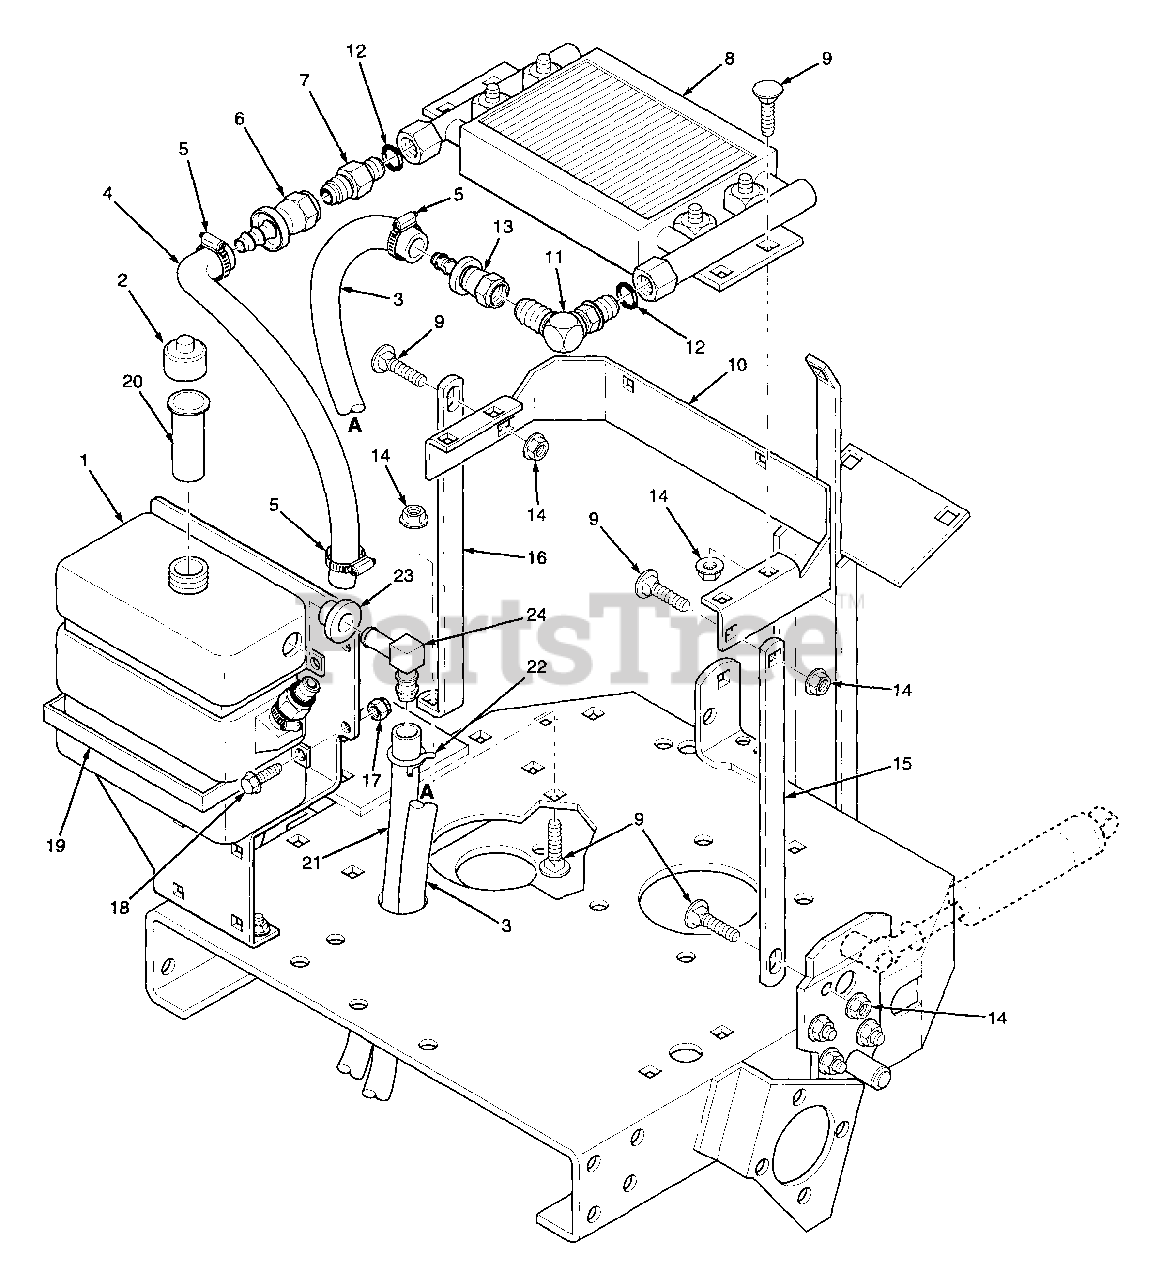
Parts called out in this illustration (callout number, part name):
1	Tank, Hydraulic
2	Cap, Hydraulic Tank
3	Hose, Pump to Oil Cooler
4	Hose, Oil Cooler to Tank
5	Clamp, Hose
6	Coupling, Flare Swivel
7	Tube, Union
8	Oil Cooler Assembly
9	Carriage Bolt, 5/16-18 x 3/4"
10	Bracket, Oil Cooler
11	Elbow, 90 Degrees
12	O-Ring
13	Coupling Flare Swivel
14	Serr. Fl. Hex Head Nut, 5/16-18
15	Brace, L.H. Cooler Support
16	Brace, R.H. Cooler Support
17	Elastic Stop Nut, 1/4-20
18	Serr. Fl. Hex Head CPSCR, 1/4-20 x 3/4"
19	Strap, Oil Tank
20	Filler Neck Insert
21	Hose, 1/4" Pushlock
23	Bushing
24	90 Degree Elbow
